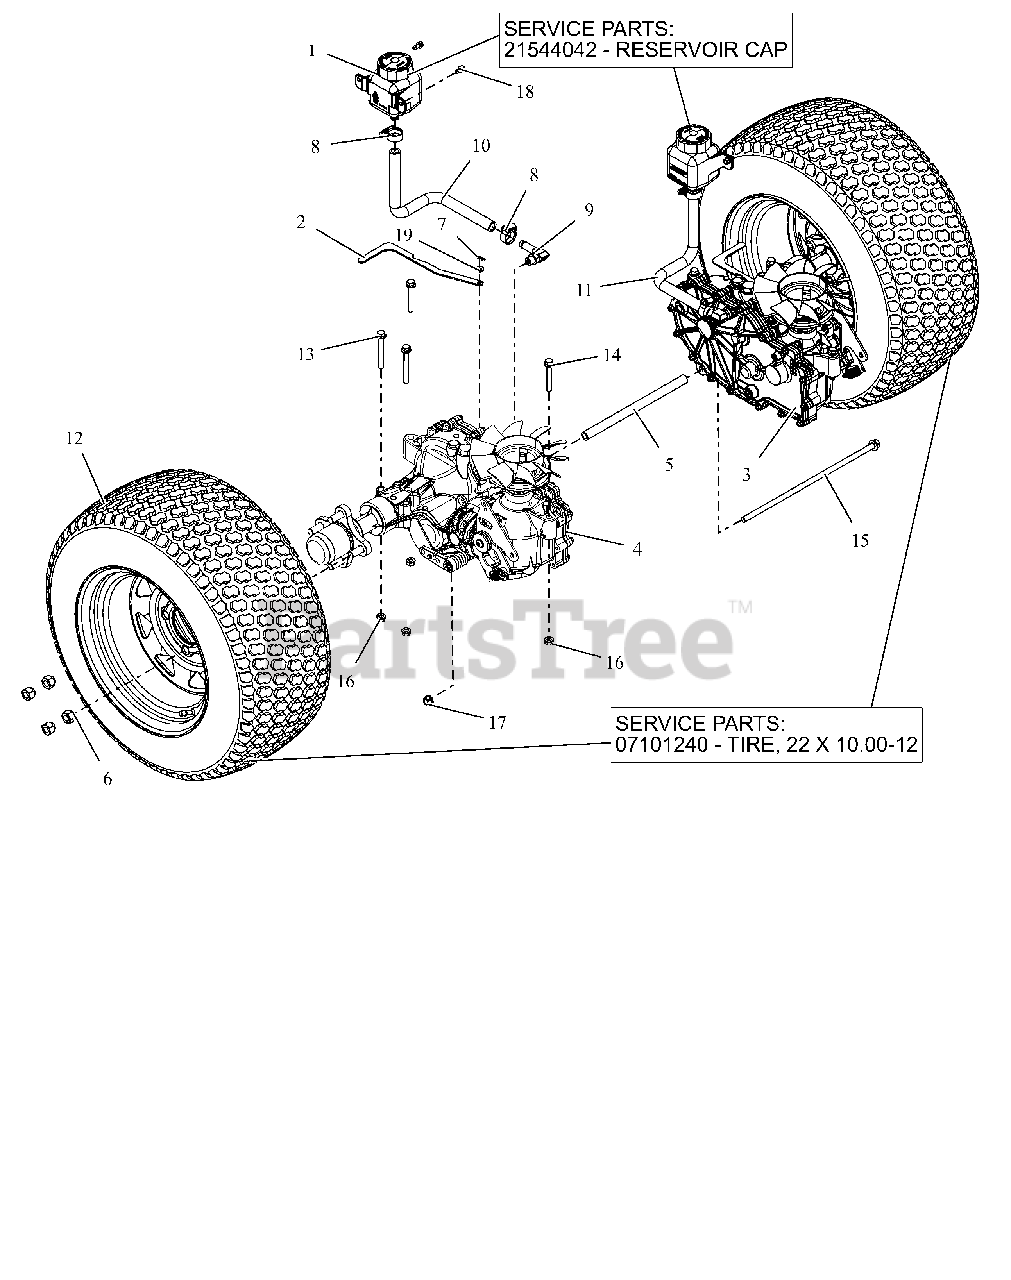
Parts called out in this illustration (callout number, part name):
1	TANK, EXPANSION
1	CAP, HYDRO RESERVOIR REPLAC.
2	BRKT, VALVE DUM
3	TRANSAXLE, ZT3200 LH
4	TRANSAXLE, RH ZT3200
5	SPCR, TRANSAXLE .406 ID X .630 OD X 9.95LG (BLACK)
6	NUT, WHEEL .50-20 ZCC
7	PIN, HAIR #225 .072X1.09
8	CLAMP,.88 DIA. HOSE
9	FITTING, HYD (90 DEG)
10	HOSE, FORMED EXPANSION -HD RH
11	HOSE, FORMED EXPANSION -HD LH
12	ASM, WHL/TIRE 22X10.00-12 K500
12	TIRE, 22X10.00-12
13	BLT,HEX-FLG .31-18X2.75 G5 ZCC
14	BLT,HEX-FLG .31-18X2.25 G5 ZCC
15	BLT, HEX-FLG 0.375-16X13 GR5 ZC120
16	NUT,LK-CTR-FLG .31-18 GF ZCC
17	NUT-LK-CTR-FLG .375-16 GF ZCC
18	SCR-TAP .25-20X.50 HWH ZCC
19	WSHR,FLT .281X.625X.065 ZCC
